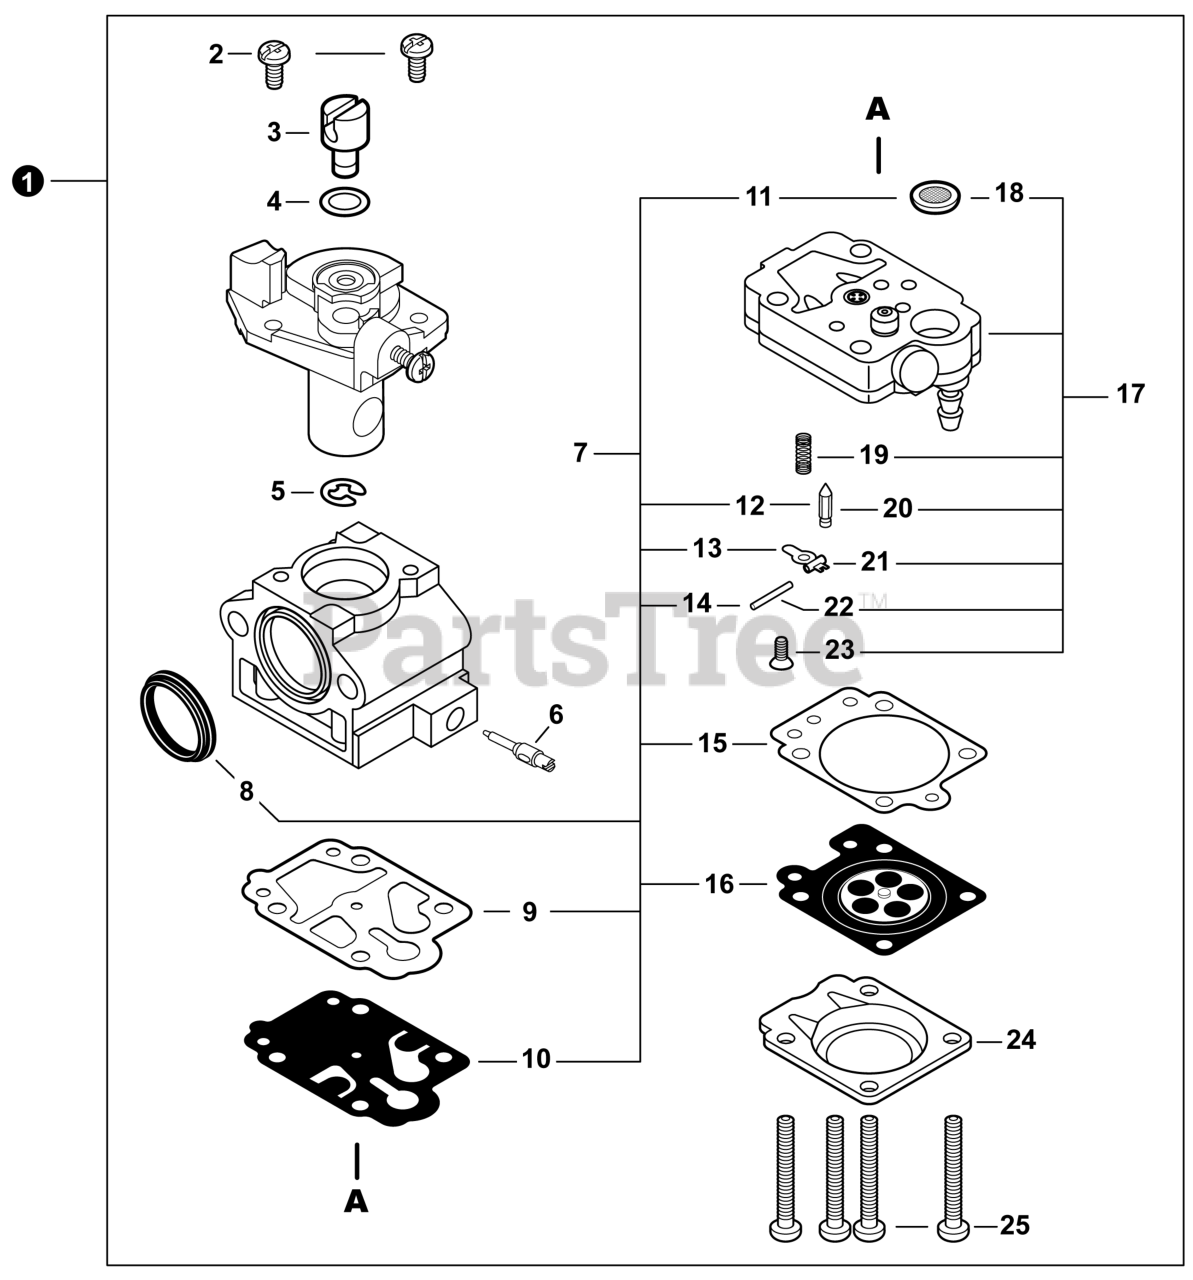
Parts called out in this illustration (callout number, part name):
1	CARBURETOR - WYK-406A
6	NEEDLE, MIXTURE
7	REPAIR KIT, CARBURETOR
8	RING, PACKING
9	GASKET, PUMP
10	DIAPHRAGM, FUEL PUMP
11	SCREEN, FUEL INLET
12	VALVE, INLET NEEDLE
13	LEVER, METERING
14	PIN, METERING LEVER
15	GASKET, METERING DIAPHRAGM
16	DIAPHRAGM, METERING
17	BODY ASSY, PUMP
18	SCREEN, FUEL INLET
19	SPRING, METERING LEVER
20	VALVE, INLET NEEDLE
21	LEVER, METERING
22	PIN, METERING LEVER
23	SCREW
24	COVER, METERING DIAPHRAGM
